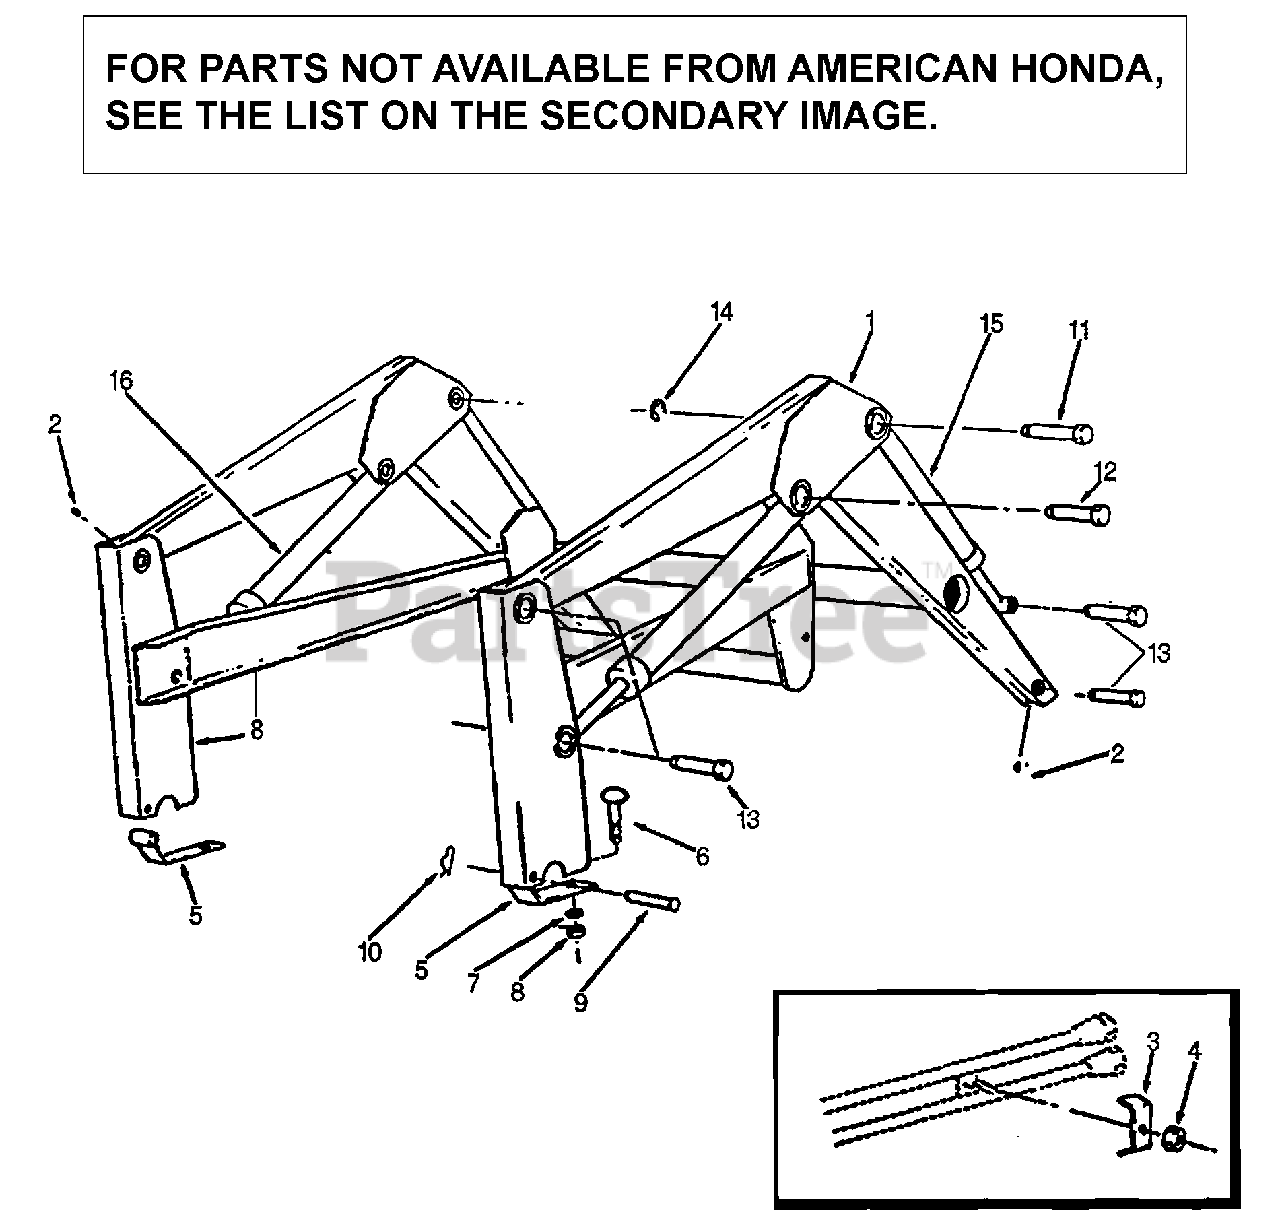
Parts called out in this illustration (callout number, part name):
2	FITTING, GREASE
5	HINGE ASSY.
6	BOLT, CARRIAGE (1/2X13X4")
9	PIN (1/2X3-5/8")
11	PIN, PIVOT (1X3-3/8")
12	PIN, PIVOT (1X3-1/4")
13	PIN, PIVOT (1X4")
14	CLIP, PIVOT PIN
15	CYLINDER ASSY., BUCKET
16	CYLINDER ASSY., BOOM
